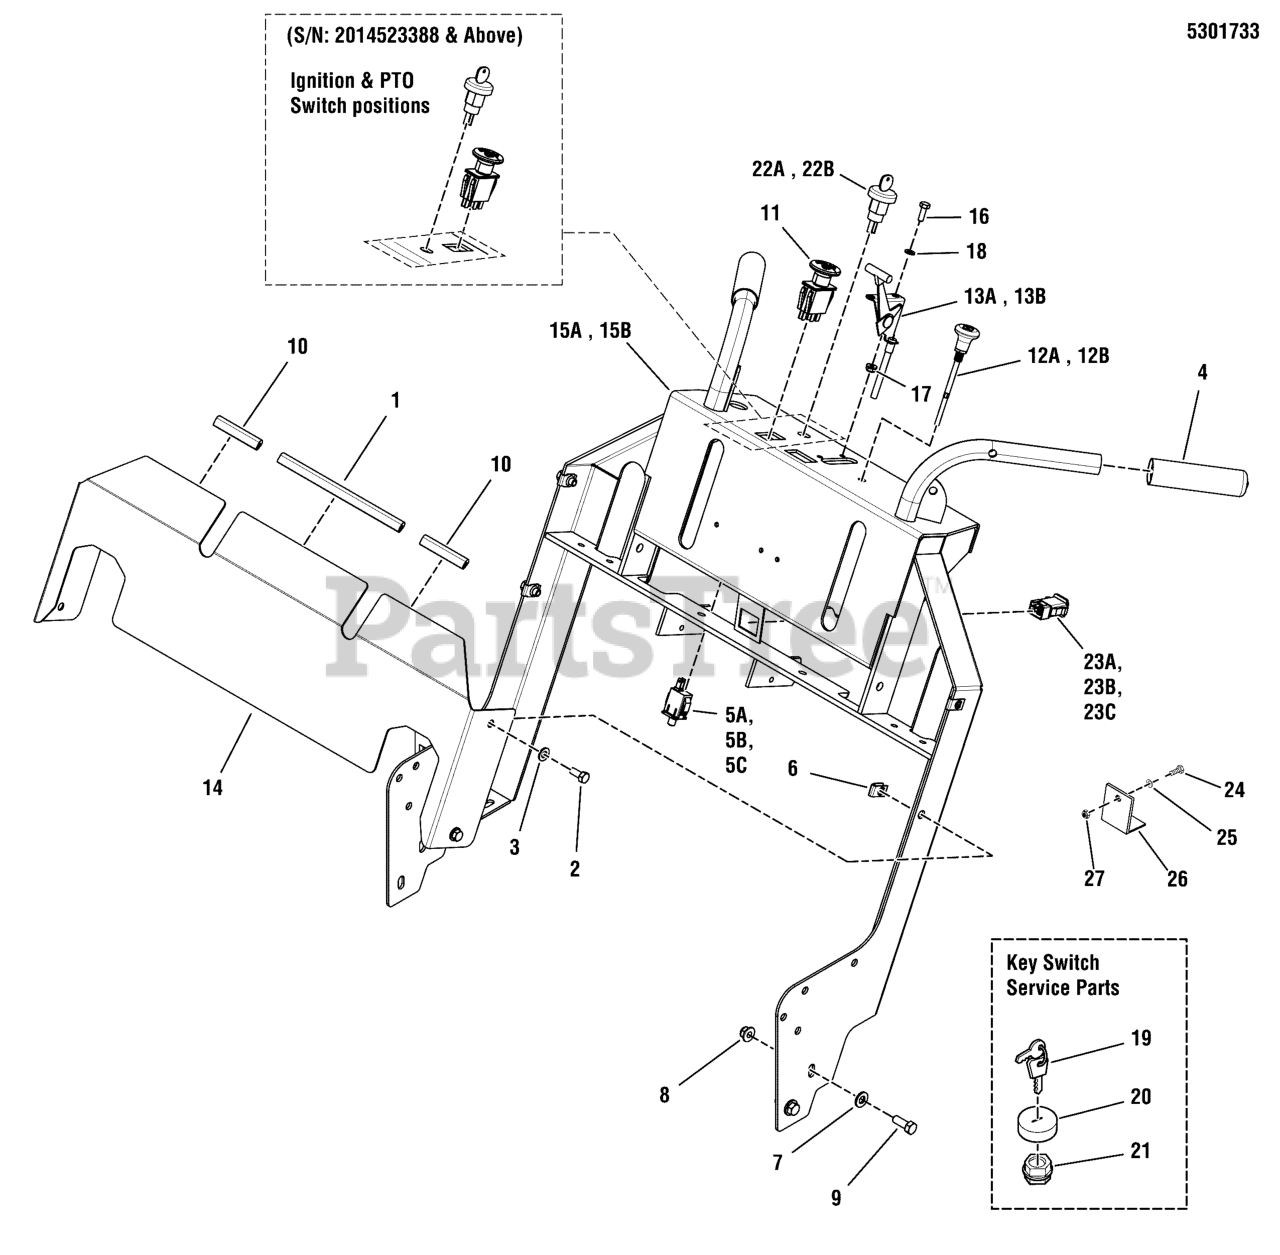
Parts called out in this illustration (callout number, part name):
1	BODY MOLDING, 8.50 LONG
2	BOLT, 5/16-18 X 3/4 GD5
3	WASHER, 5/16" SAE
4	GRIM, FOAM, .940" ID X 4.62" X .187", BLK
6	BODY CLIP, 5/16-18-7GA MATERIAL
7	WASHER, 3/8 GD.9 FLAT
8	NUT, 3/8-16 HEX NYLOCK FLANGE
9	BOLT, 3/8-16 X 1" GD5 CZ
10	BODY MOLDING, 3" LONG
11	SWITCH, BLADE ENGAGEMENT
14	PLATE, HANDLE BAR COVER, SW20-52 - RED
16	BOLT, 1/4-20 X 3/4 GD5 YZ
17	NUT, 1/4-20 HEX NYLOCK FLANGE
18	WASHER, 1/4 SAE
19	KEY, IGNITION MOLDED SET
20	COVER, PLASTIC, SNAP ON
21	PLASTIC NUT
24	BOLT, 1/4-20 X 3/4 GD5 YZ
25	WASHER, 1/4 SAE
26	BRACKET, RELAY HOLDER - BLK
27	NUT, #10-24 HEX NYLOCK LOCK
